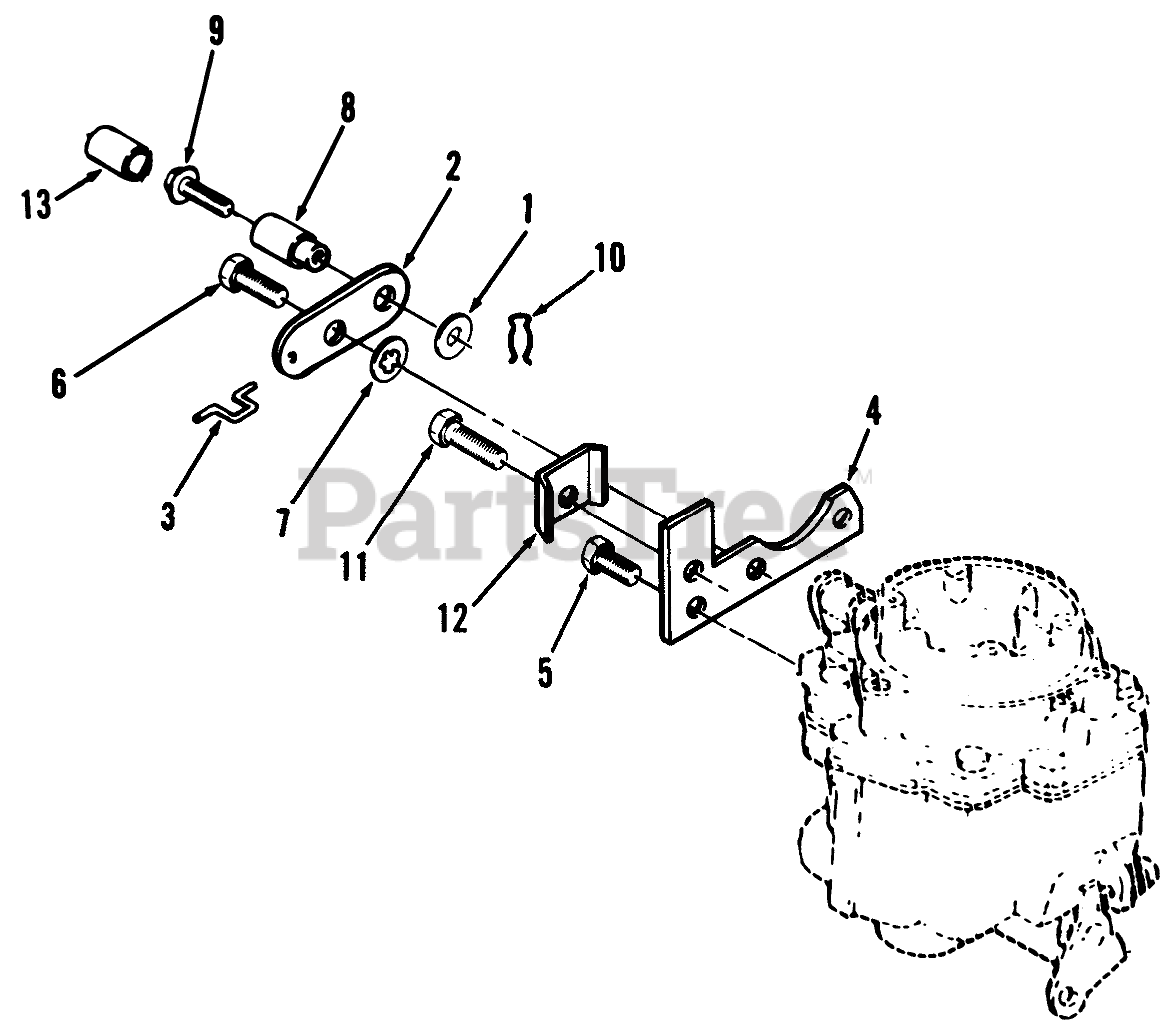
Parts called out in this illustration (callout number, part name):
1	Washer
2	SWIVEL-CHOKE
3	LINK-CHOKE
4	BRACKET
5	Bolt
6	BOLT-SHOULDER
7	Lockwasher
8	SWIVEL
9	Bolt
10	PIN-COTTER
11	Bolt
